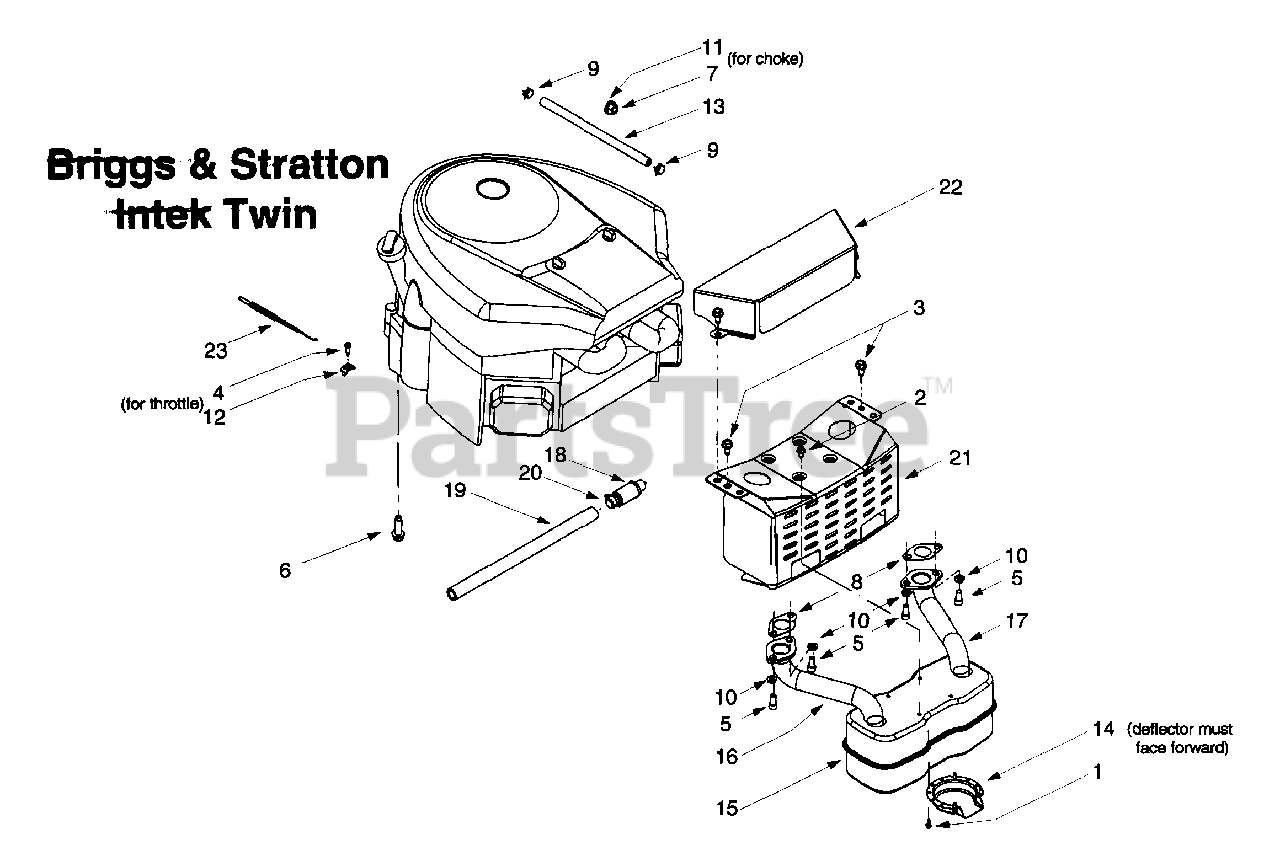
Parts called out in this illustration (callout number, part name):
1	Self Tapping Screw, #8-32 x .375
2	Self Tapping Screw, 1/4-20 x .5
3	Self Tapping Screw, 5/16-18 x .625
4	Screw, #10-32 x .625
5	Socket Cap Screw, 5/16-18 x .625
6	Self Tapping Screw, 3/8-16 x 1.25
7	Hex Nut, 3/8-16
8	Exhaust Gasket
9	Hose Clamp
10	Lock Washer, 5/16
11	Lock Washer, 3/8 x .56 x .018
12	Casing Clamp
13	Fuel Line Hose
14	Muffler Deflector
15	Muffler
16	RH Exhaust Pipe
17	LH Exhaust Pipe
18	Oil Drain Valve
19	Oil Drain Hose
20	Oil Drain Cap
22	Engine Heat Shield
23	Throttle Cable
